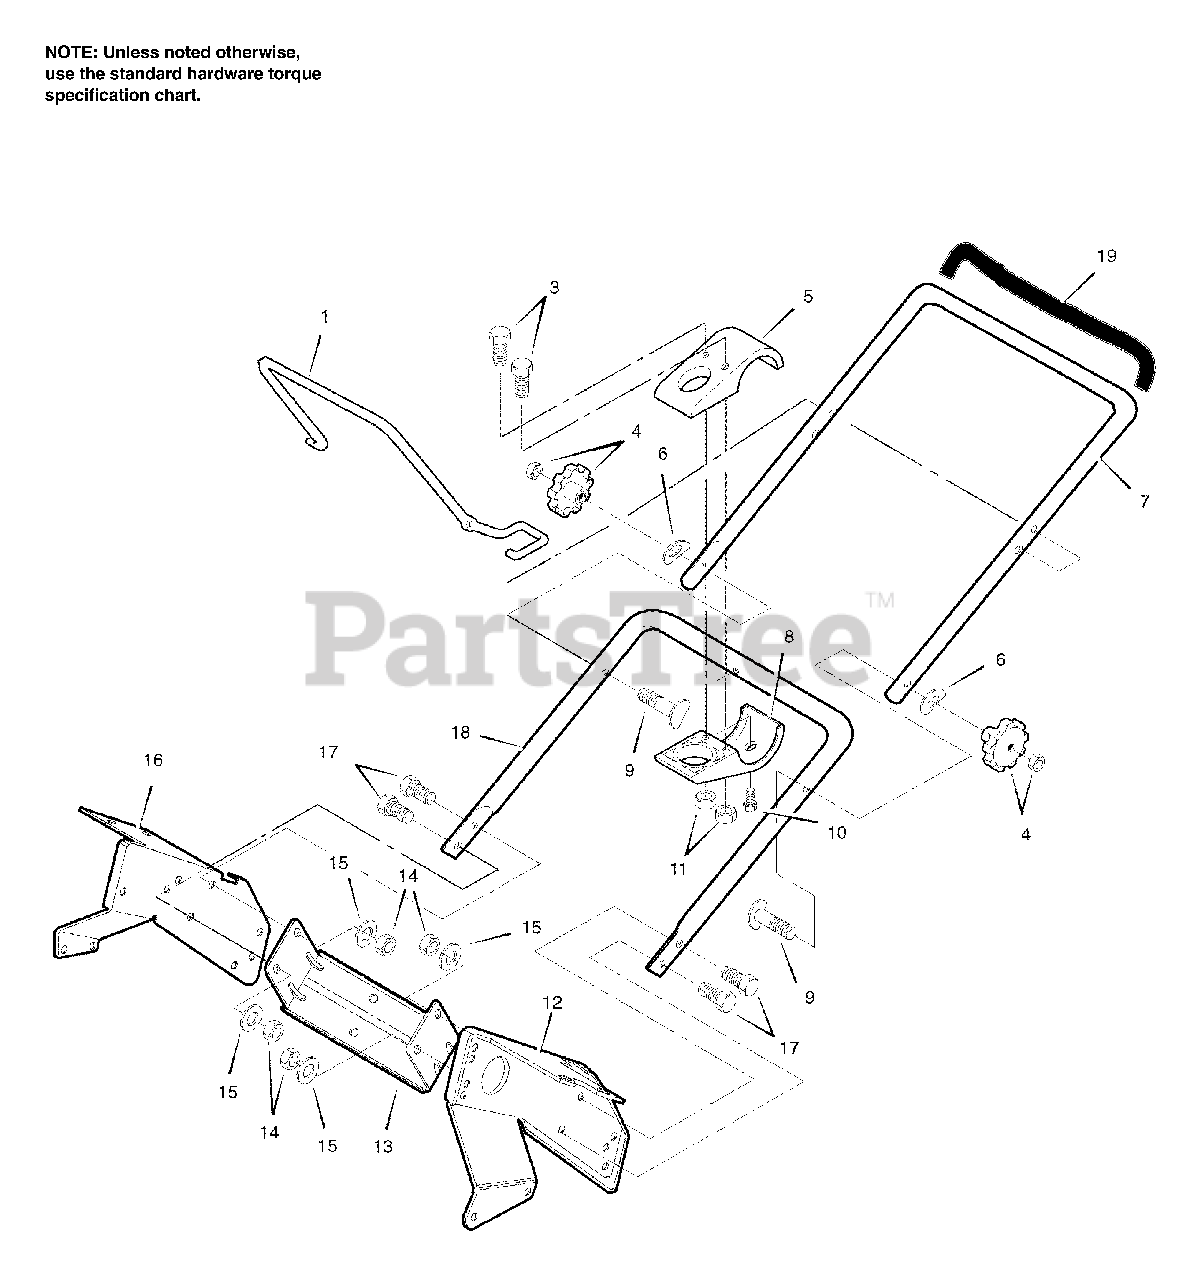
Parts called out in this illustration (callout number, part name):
3	SCREW 10-24 x 1.00
5	BRACKET, UPPER CRANK
6	WASHER, FORMED
7	HANDLE, UPPER w/FOAM
8	BRACKET, LOWER CRANK
9	BOLT, FORMED HEAD
10	SCREW .25-20 x .62
11	NUT, LOCK 10-24
12	PLATE, REAR MOUNT LH
13	FRAME SUPPORT
14	NUT, LOCK .31-18
15	WASHER, LOCK
16	PLATE, REAR MOUNT RH
17	SCREW .31-18 x .75
18	LOWER HANDLE
19	TUBING, FOAM
